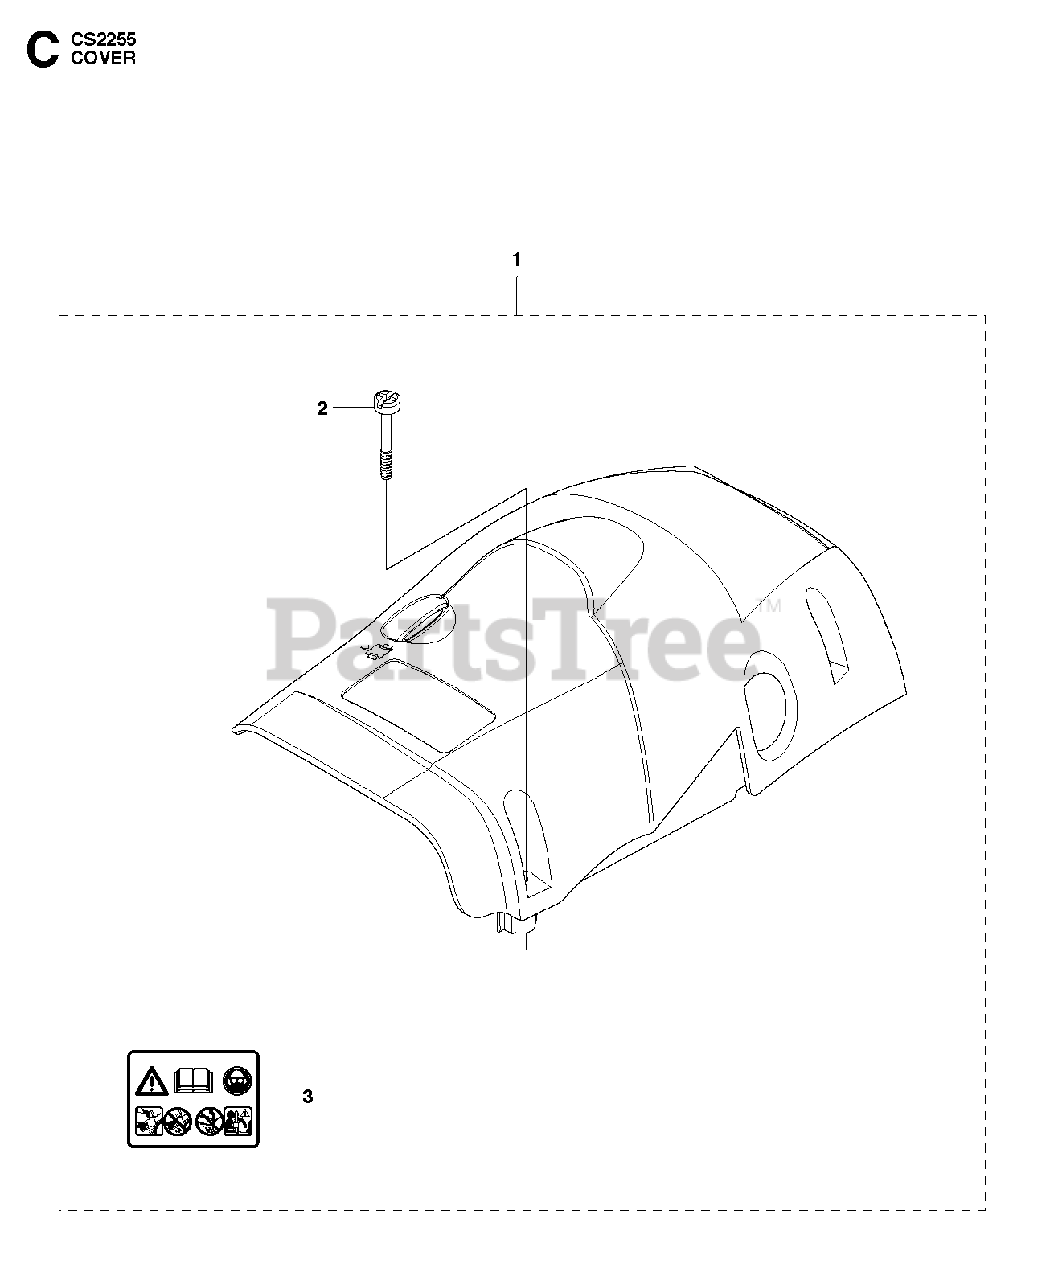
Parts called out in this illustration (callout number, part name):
1	CYLINDER COVER
2	SCREW
3	DECAL
